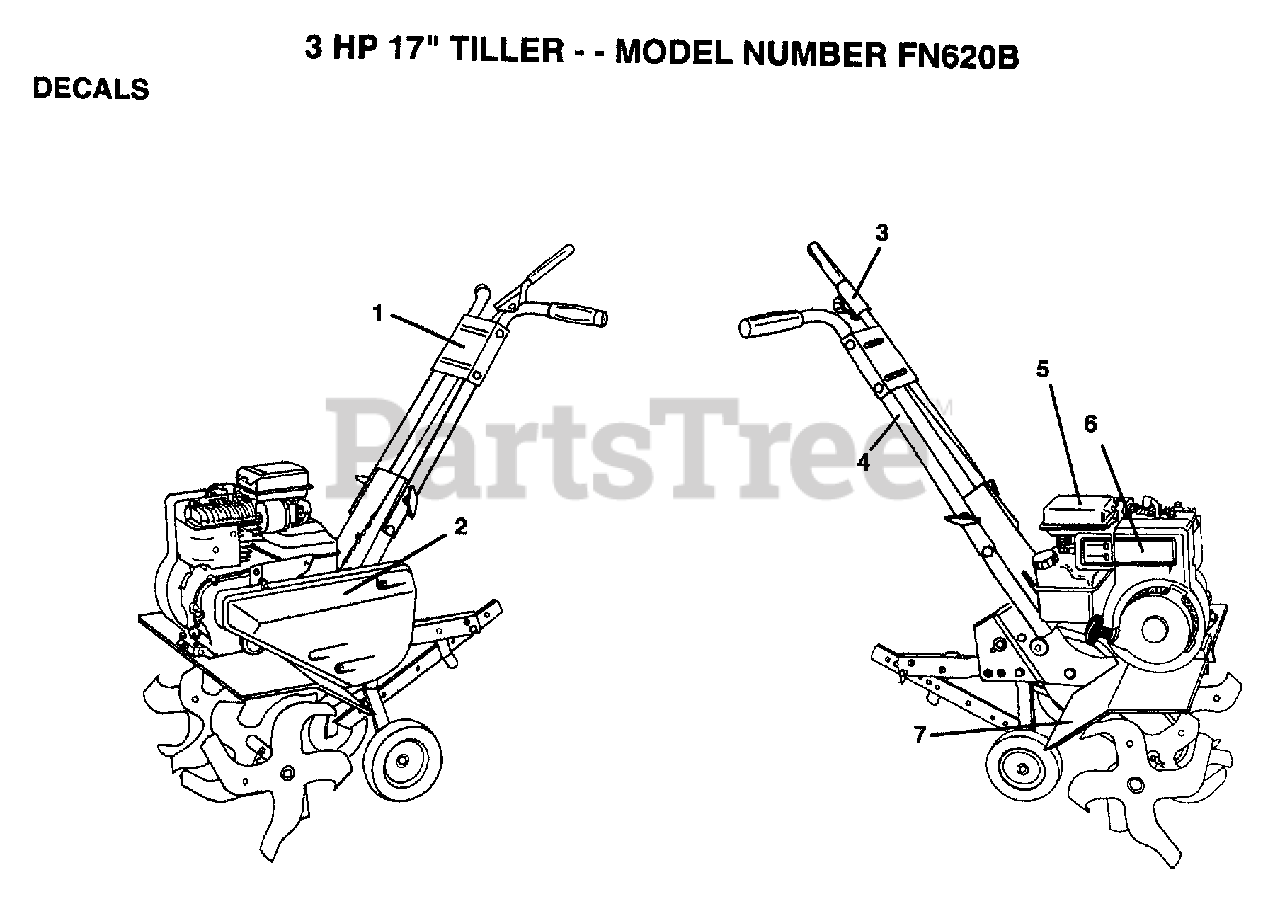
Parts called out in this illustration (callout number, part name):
1	DECAL HANDLE BRKT
3	DECAL TI
4	DECAL TI
5	DECAL TI
6	"DECAL,ENG HP"
